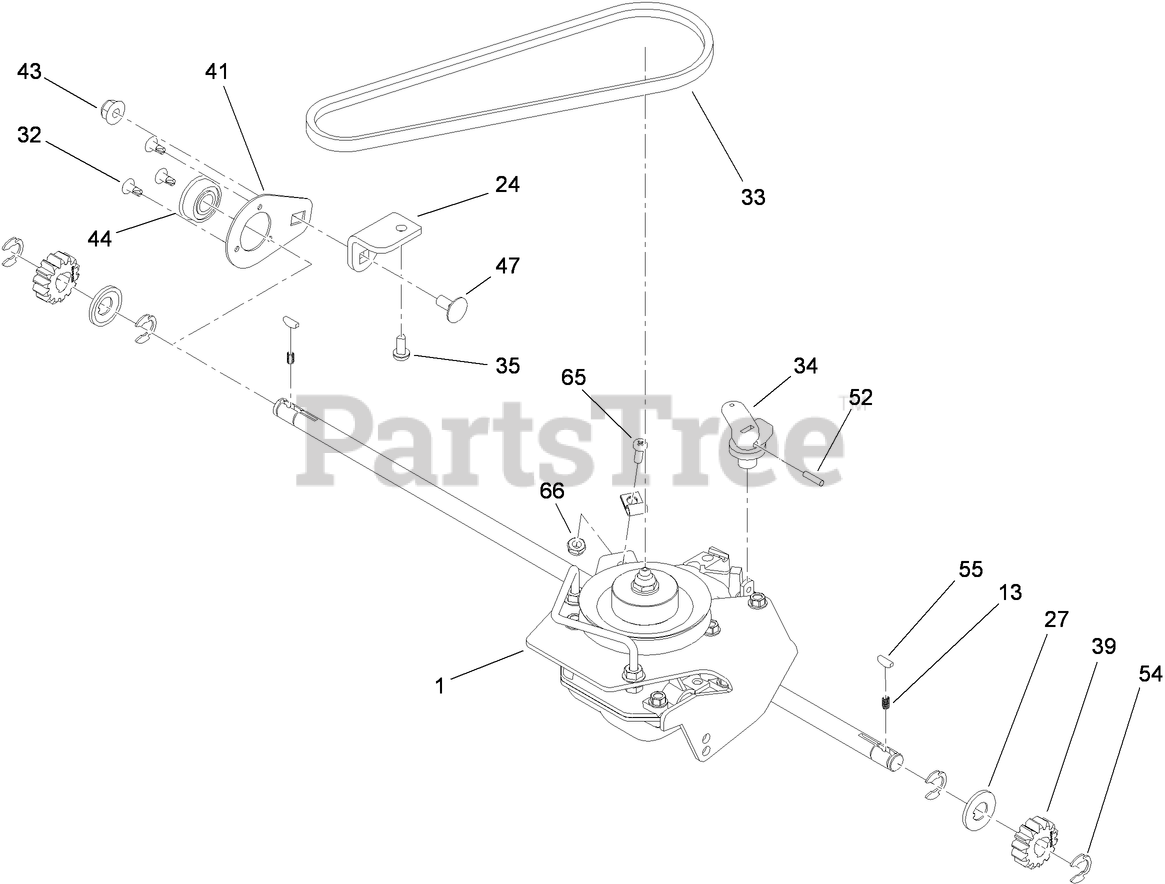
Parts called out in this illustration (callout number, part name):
1	GEAR CASE ASM
13	SPRING-COMPRESSION
24	BRACKET-BEARING, PLATED
27	WASHER-THRUST, OUTER
32	SCREW-TAP
33	BELT-V, TRACTION
34	LEVER-SHIFT
35	SCREW-HWH
39	GEAR-PINION
41	PLATE-BEARING
43	NUT-HF, NI
44	BEARING-BALL
47	SCREW-CARR
52	PIN-COIL
54	RING-RETAINING
65	SCREW-HSBH
66	NUT-LOCK, NI
